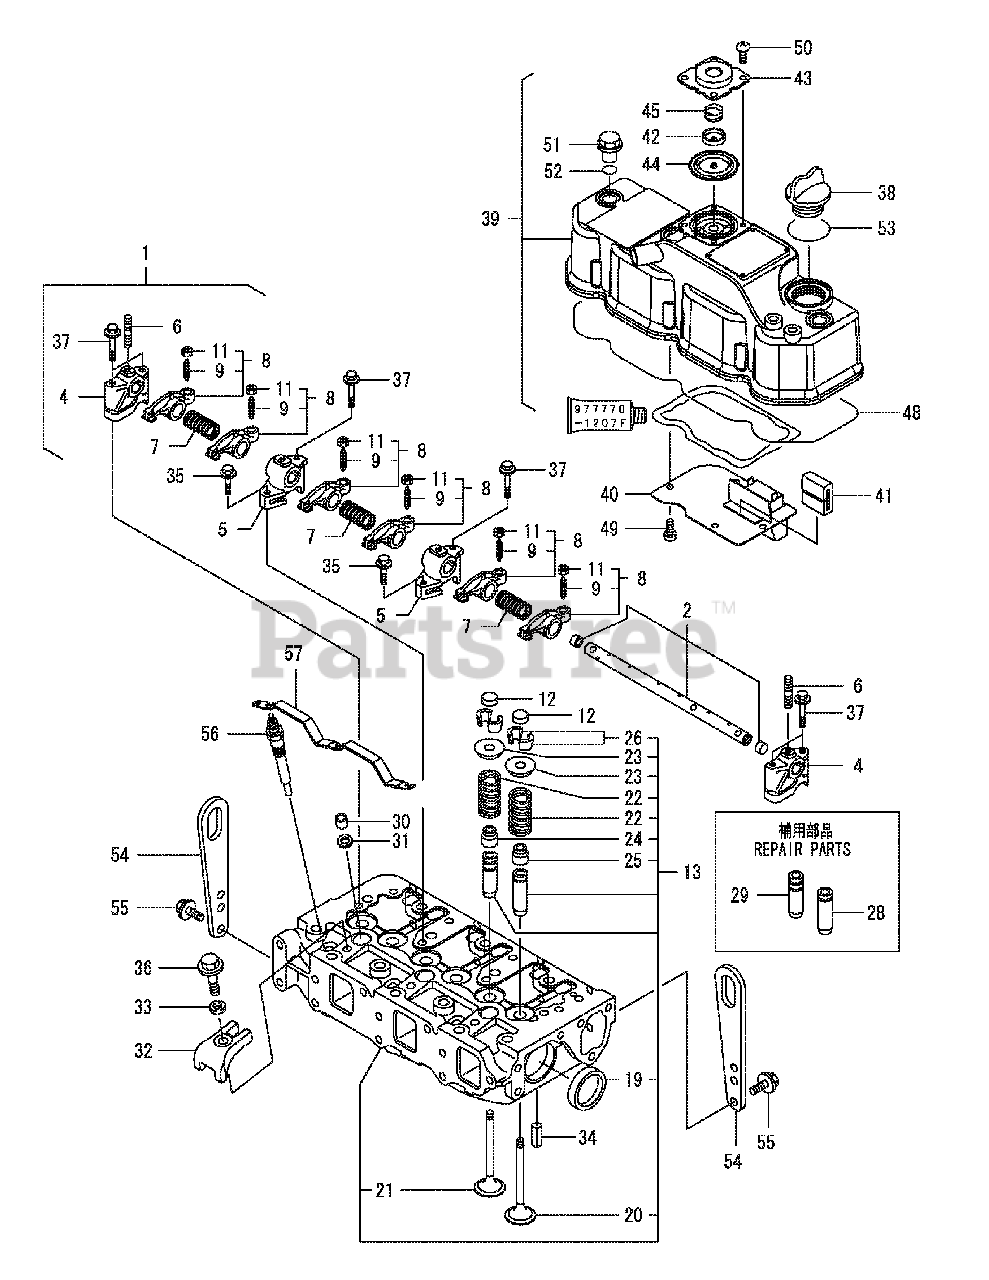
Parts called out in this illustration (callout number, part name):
1	Rocker Shaft Assembly
2	Rocker Arm Shaft
8	Rocker Arm Assembly
9	Valve Adjust Screw
13	Cylinder Head Assembly
23	Spring Retainer
24	Valve Stem Seal
25	Valve Stem Seal
28	Intake Valve Guide
29	Exhaust Valve Guide
30	Nozzle Protector
32	Nozzle Retainer
33	Injector Washer
34	Spring Pin, 6 x 12
39	Head Bonnet Assembly
41	Breather Baffle
43	Diaphragm Cover
45	Diaphragm Spring
49	Screw, M5 x 10
50	Screw, M5 x 10
52	O-Ring, 1A P-12.0
53	O-Ring, 1A P-32.0
57	Glow Plug Connector
